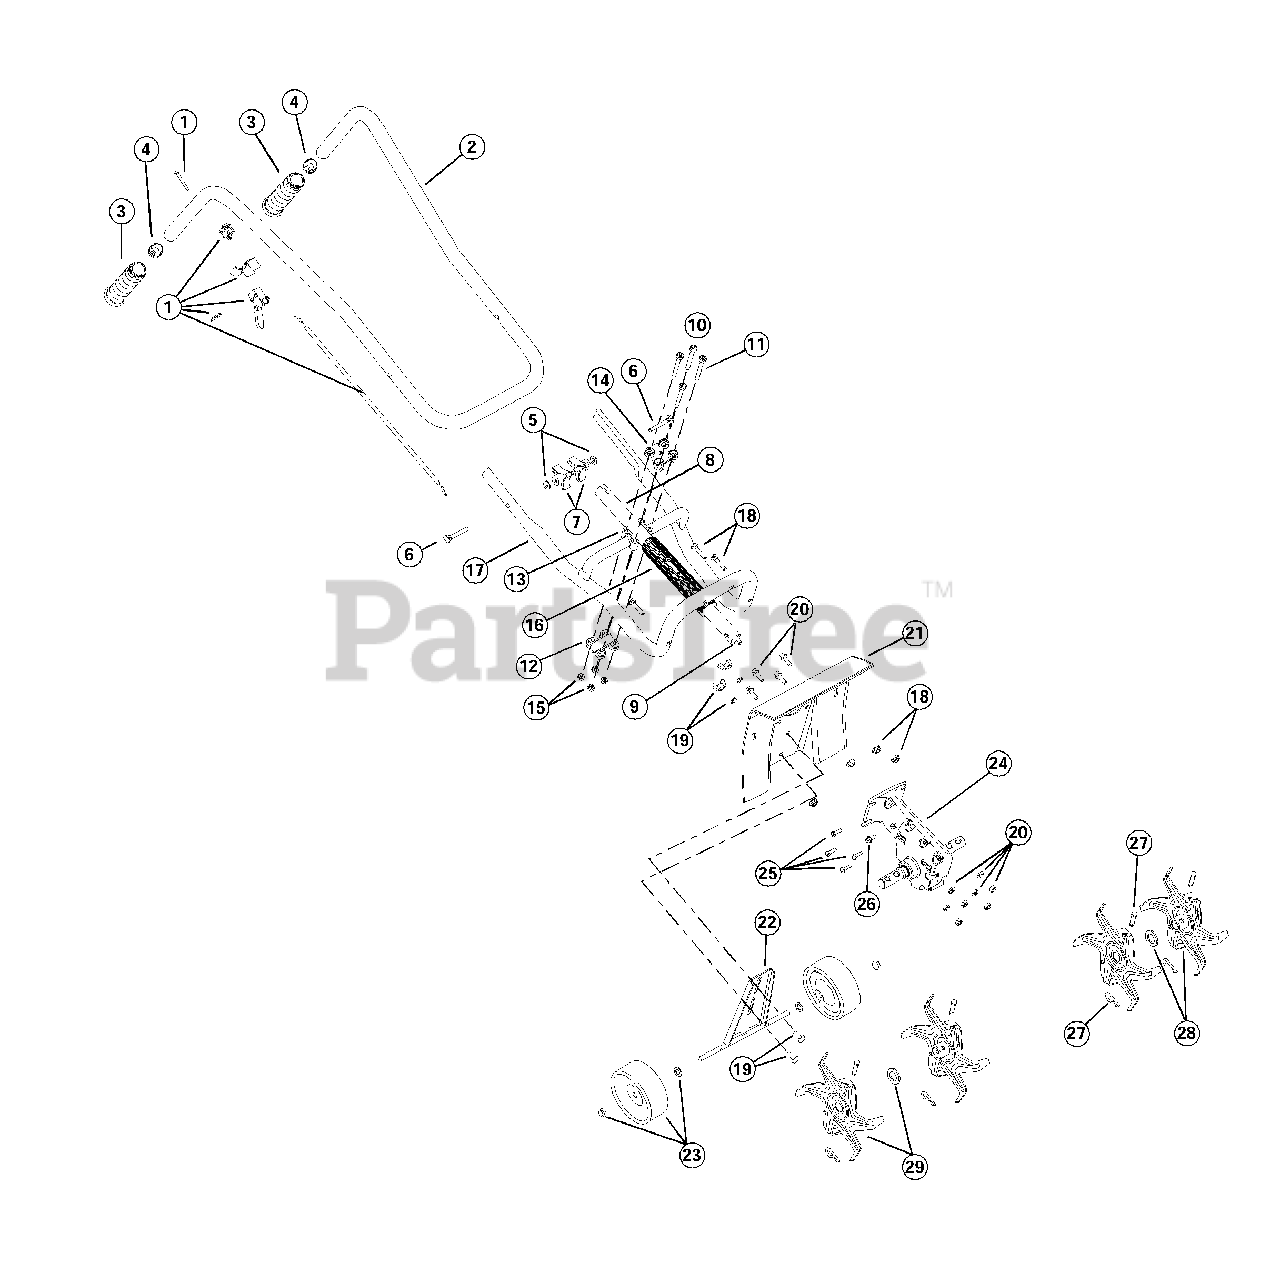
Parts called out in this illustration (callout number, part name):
1	Throttle Trigger and Cable Assembly
2	Handle Bar Assembly, Upper
4	Tube Closure
5	Washer
7	Knob, 3 prong
8	Drive Shaft Housing Assembly
9	Flexible Drive Shaft
10	Handle Bracket Assembly
12	Upper Handle Clamp
13	Middle Handle Clamp
14	Lower Handle Clamp
17	Lower Handle Bar
18	Hardware, Handle Bar Mounting (lower)
19	Wheel Bracket Mounting Hardware
20	Guard Mounting Hardware
22	Wheel Bracket Assembly
23	Wheel Assembly
24	Gear Box Assembly
26	Sleeve Retainer Bolt
27	Tine Fastener Assembly
28	Tine Assembly (Left Outer or Right Inner)
29	Tine Assembly (Left Inner or Right Outer)
